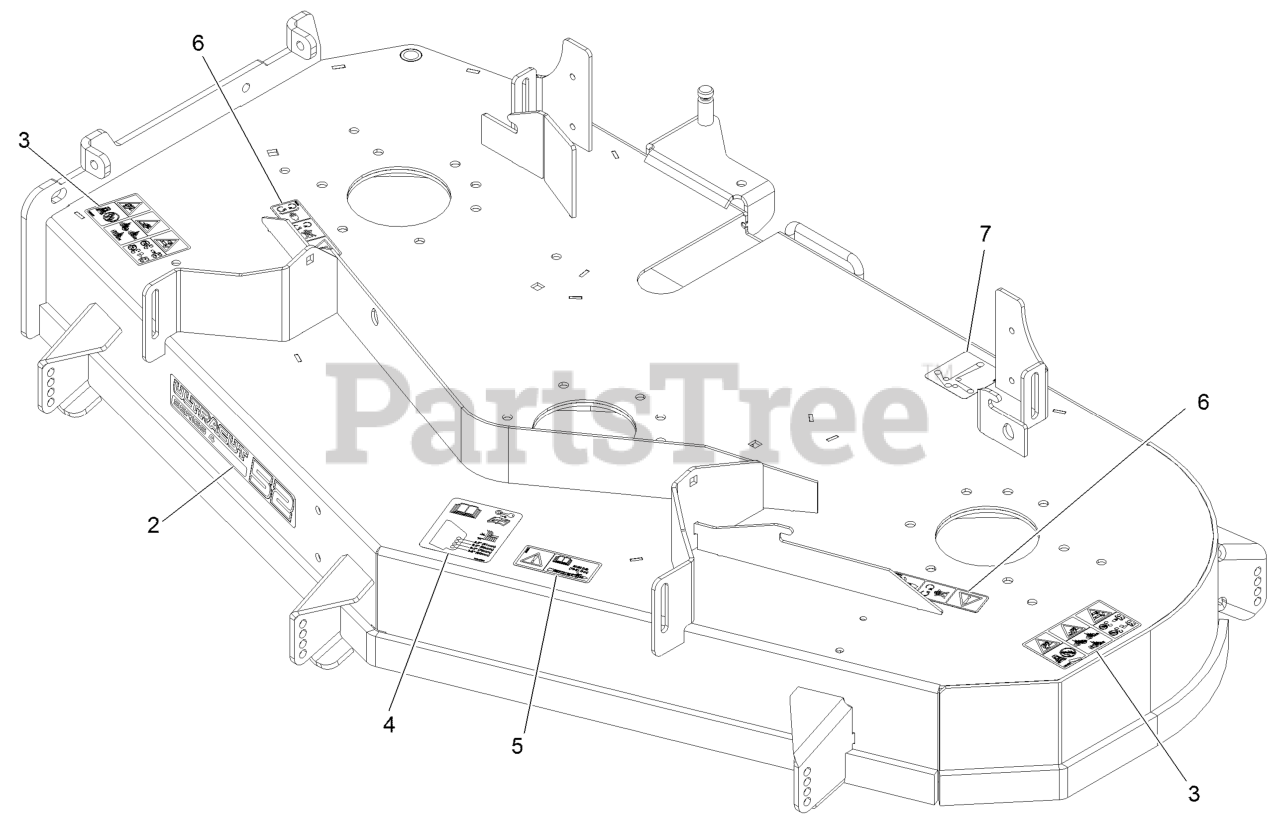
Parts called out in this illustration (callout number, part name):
2	DECAL, 524
3	DECAL-DANGER THROWN OBJECTS
4	DECAL-ROLLER, ANTI-SCALP
5	DECAL-BOLT TORQUE
6	DECAL-COVER, MISSING
7	DECAL-ROUTING, BELT
